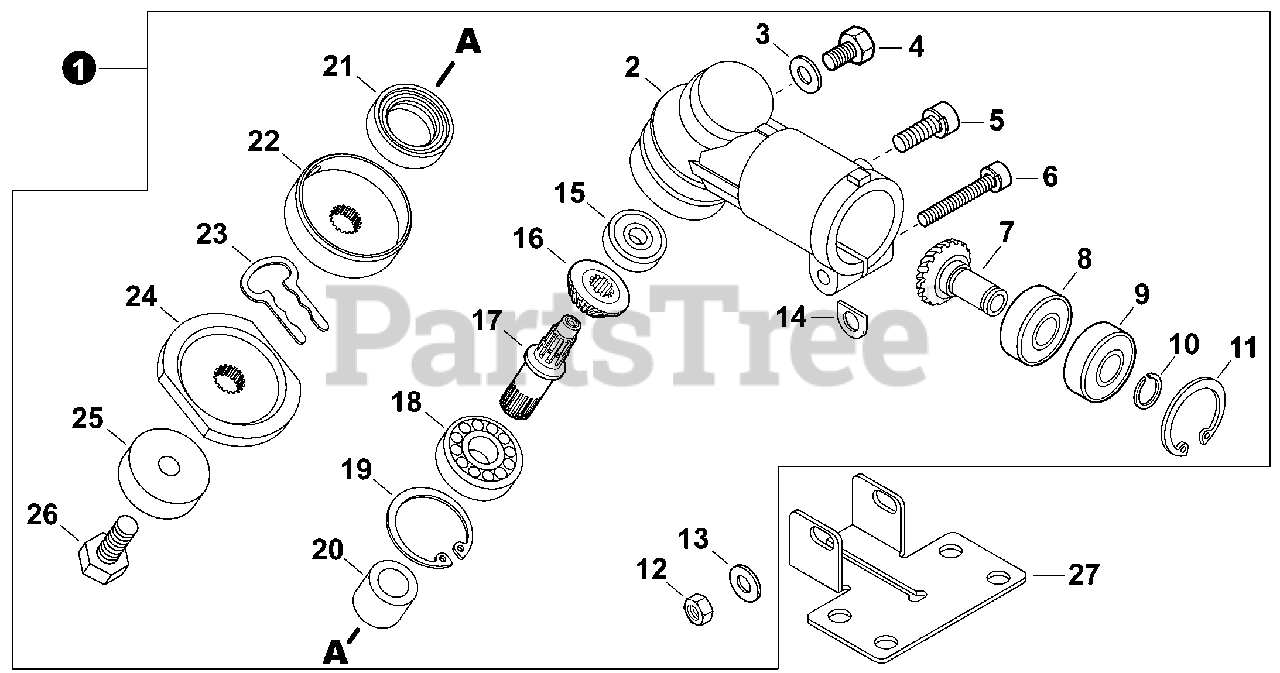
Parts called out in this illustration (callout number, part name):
1	GEAR CASE ASSY
2	HOUSING, GEAR CASE
4	BOLT M6x10
5	BOLT 5x16
6	BOLT M5x35
7	GEAR, PINION
8	BEARING, BALL 608
9	BEARING, BALL 608ZZ
10	E-RING 8
11	RING, SNAP ?22
13	WASHER 5.5x12x0.8
14	D-WASHER
15	BEARING, BALL 626 DDU
16	GEAR, BEVEL
17	SHAFT, GEAR
18	BEARING, BALL 6000
19	RING, SNAP ?26
21	SEAL, OIL
22	PLATE, ADAPTOR - UPPER
23	CLIP, BLADE
24	PLATE, ADAPTOR - LOWER
25	GUARD, BOLT
26	BOLT M7x18
27	PLATE, SHIELD MOUNTING
